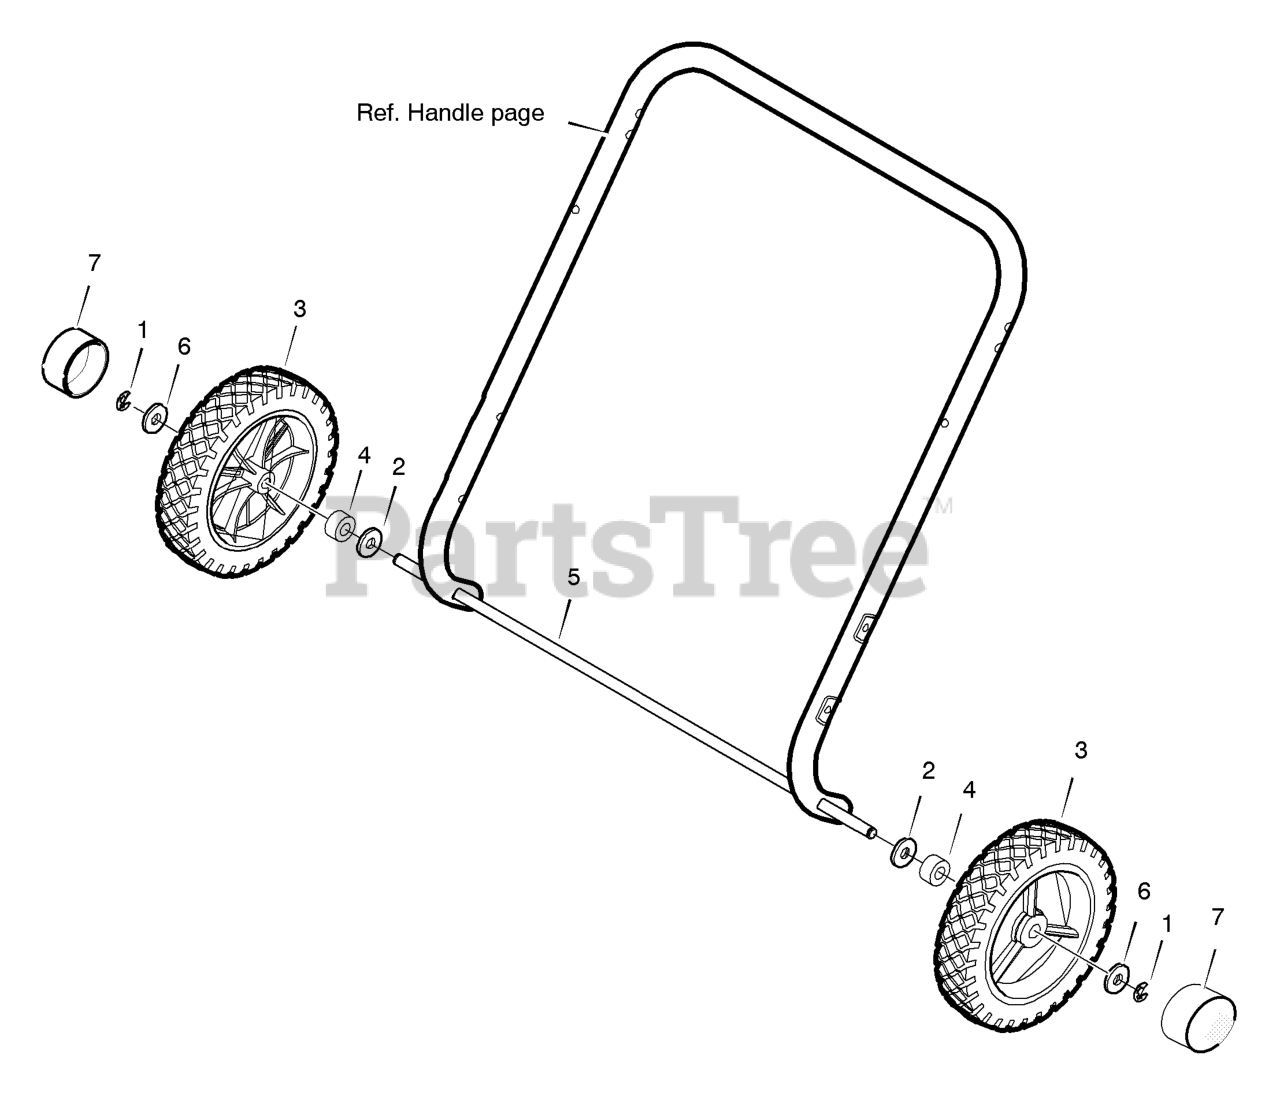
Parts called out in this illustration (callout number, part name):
1	Retainer, E-Ring
2	Washer
3	Wheel and Tire 7" x 1.50"
4	Sleeve, Spacer
5	Rod, Axle
7	Cap, Hub
